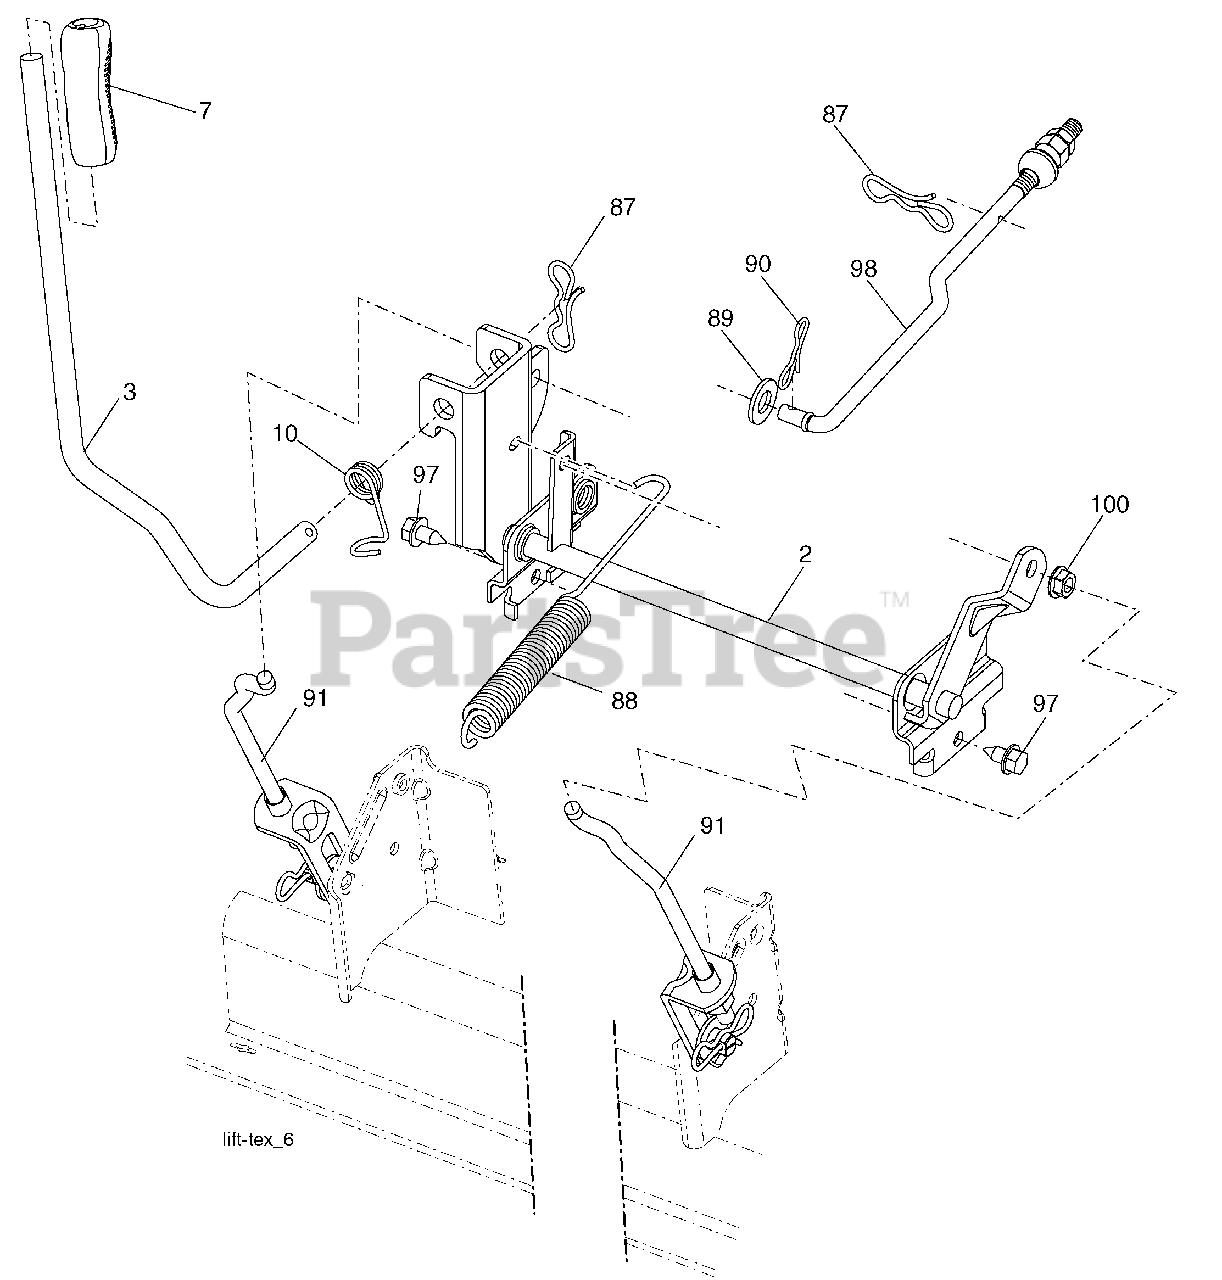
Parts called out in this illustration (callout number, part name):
2	Shaft Asm., Lift
3	Lever Asm., Lift Rh
7	Grip, Lever
10	Spring Torsion
87	Pin Cotter 7/16 Bow Tie Lock
88	Spring Lift Assist
89	Washer Clear Zinc
90	Pin Cotter 5/16 Bow Tie Lock
91	Link Asm. Lift Rear
97	Screw 3/8-16 x .75 R.Z
98	Link Lift Susp. Front Mower
100	Nut Centerlock 3/8-16 unc
